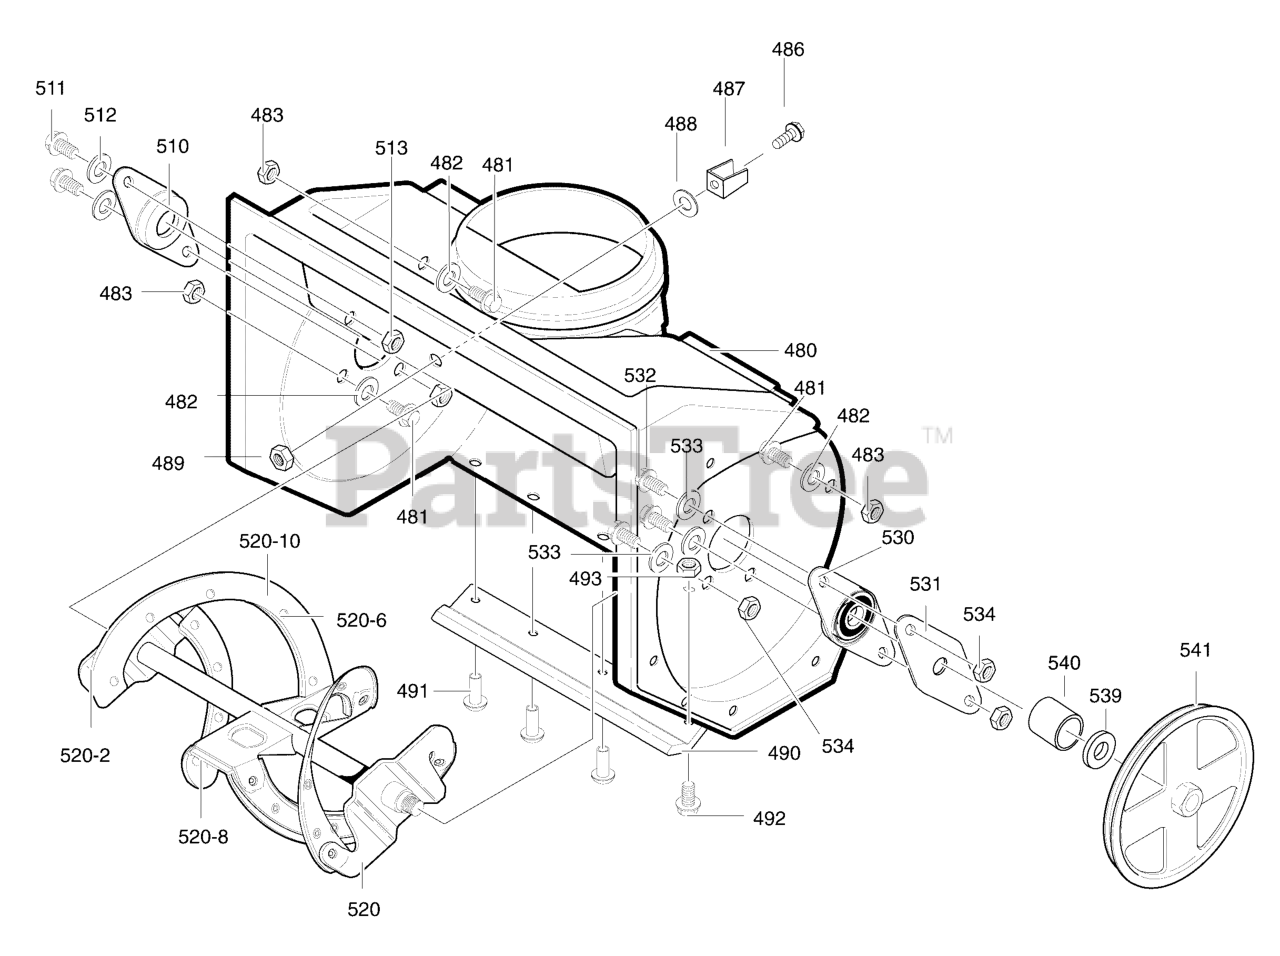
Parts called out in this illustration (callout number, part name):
480	HOUSING ASSEMBLY
481	SCREW, 1/4-20 x .75
482	FLATWASHER
483	NUT, 1/4-20
486	SCREW, 1/4-20 x .63
487	BRACKET, STOP
488	FLATWASHER
489	NUT, 1/4-20
490	SCRAPER BAR
492	SCREW, 1/4-20 x .75
493	NUT, 1/4-20
510	FLANGE BEARING
511	SCREW, 1/4-20 x 1.00
512	FLATWASHER
513	NUT, 1/4-20
520	AUGER ASSEMBLY
520-2	AUGER BLADE
520-8	CENTER BLADE
520-10	AUGER & BLADE SUPPORT
530	BEARING & PLATE ASSEMBLY
531	BEARING RETAINER
532	SCREW, 1/4-20 x 5/8
533	FLATWASHER, .281 x .63 x .065
534	NUT, 1/4-20
539	FLATWASHER
540	SPACER, SLEEVE
541	PULLEY, POLY V -AUGER
